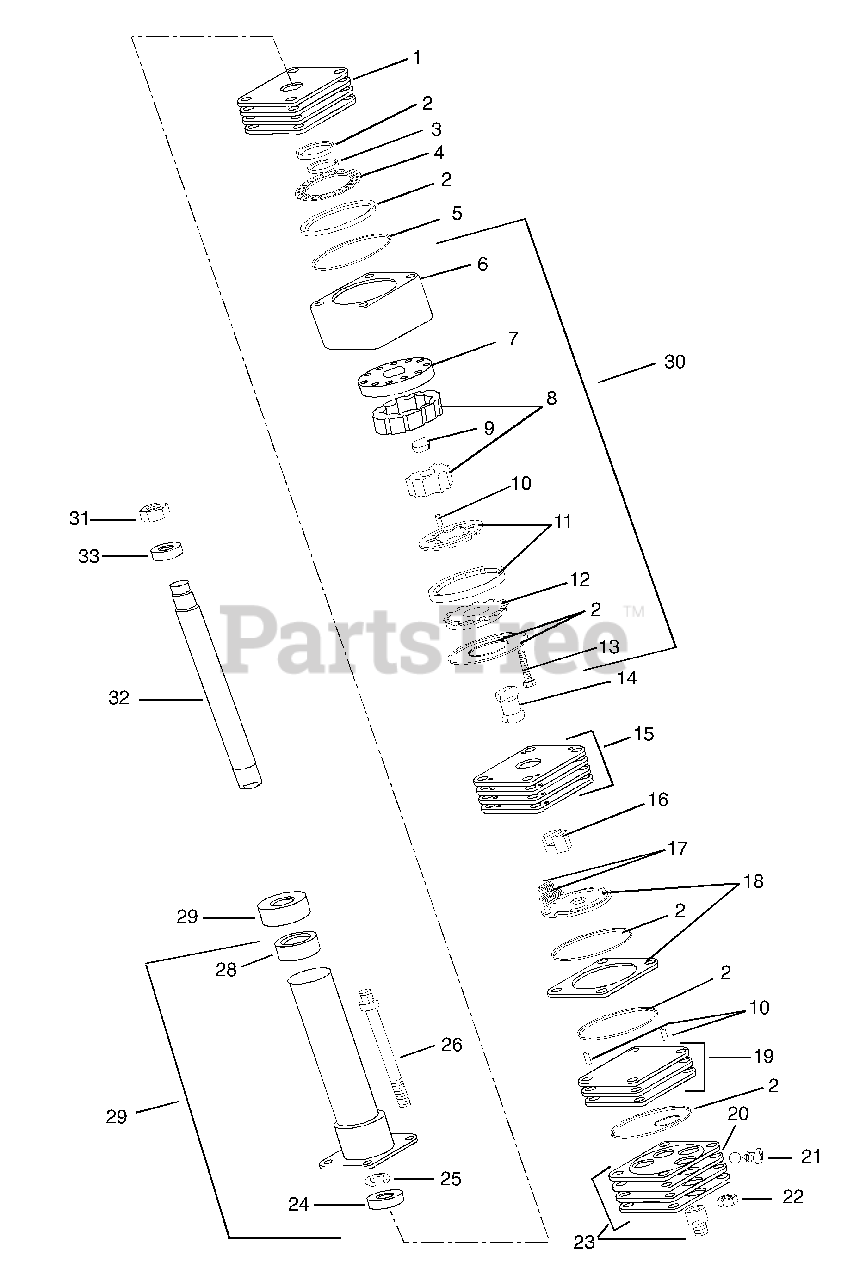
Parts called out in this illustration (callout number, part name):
1	UPPER COVER PLATE
2	REPAIR KIT, ROSS POWER STEER
3	SEAL SPACER
4	THRUST BEARING
5	SPACER-ROSS SERVICE
6	METERING RING
7	DRIVE PLATE
9	SPACER-ROSS SERVICE
10	NEEDLE ROLLER SERVICE ASS'Y
11	COMMUTATOR & RING ASS'Y
12	COMMUTATOR COVER
13	SCR-SPECIAL ROSS
14	DRIVE LINK
15	ISOLATION MANIFOLD
16	HEX DRIVE
17	SPRING SERVICE ASS'Y
18	VALVE & RING ASS'Y
19	PORT MANIFOLD
20	BALL - STEEL
21	PLUG & O-RING ASS'Y
22	NUT-LK-CTR .312-24 PL
23	PORT COVER
25	RG-RTNG ROSS #401465
26	STUD-SPECIAL SV ROSS
27	INPUT SHAFT SERVICE ASS'Y
28	COLUMN BEARING SET
30	METERING ASS'Y
31	@NUT-LK-NYL .625-18 YWZC
32	UPPER COVER & JACKET TUBE ASS'
33	DUST COVER
